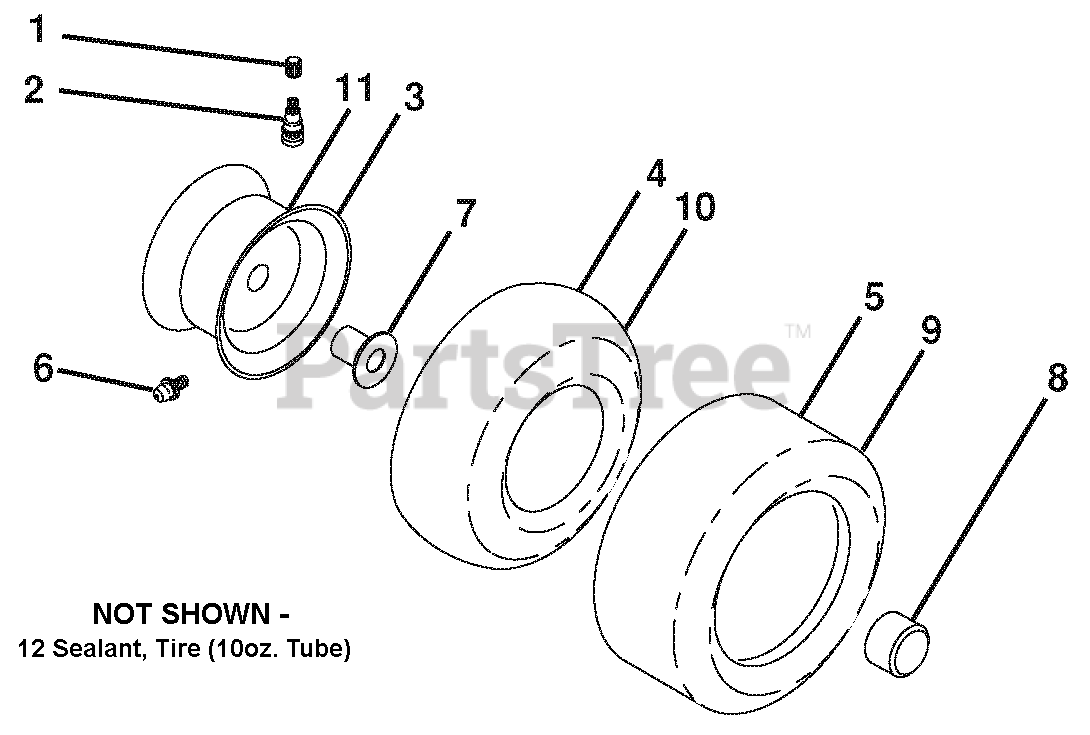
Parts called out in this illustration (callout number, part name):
1	CAP.VALVE.TIRE
2	STEM.VALVE
3	RIM ASM FRONT
4	TUBE, FRONT
6	FITTING, GREASE
7	BEARING FLANGE
8	CAP AXLE
9	TIRE, R. TS. 24 X 12-12
10	TUBE, REAR
11	RIM ASM REAR
12	SEALANT, TIRE (10 OZ. TUBE)
